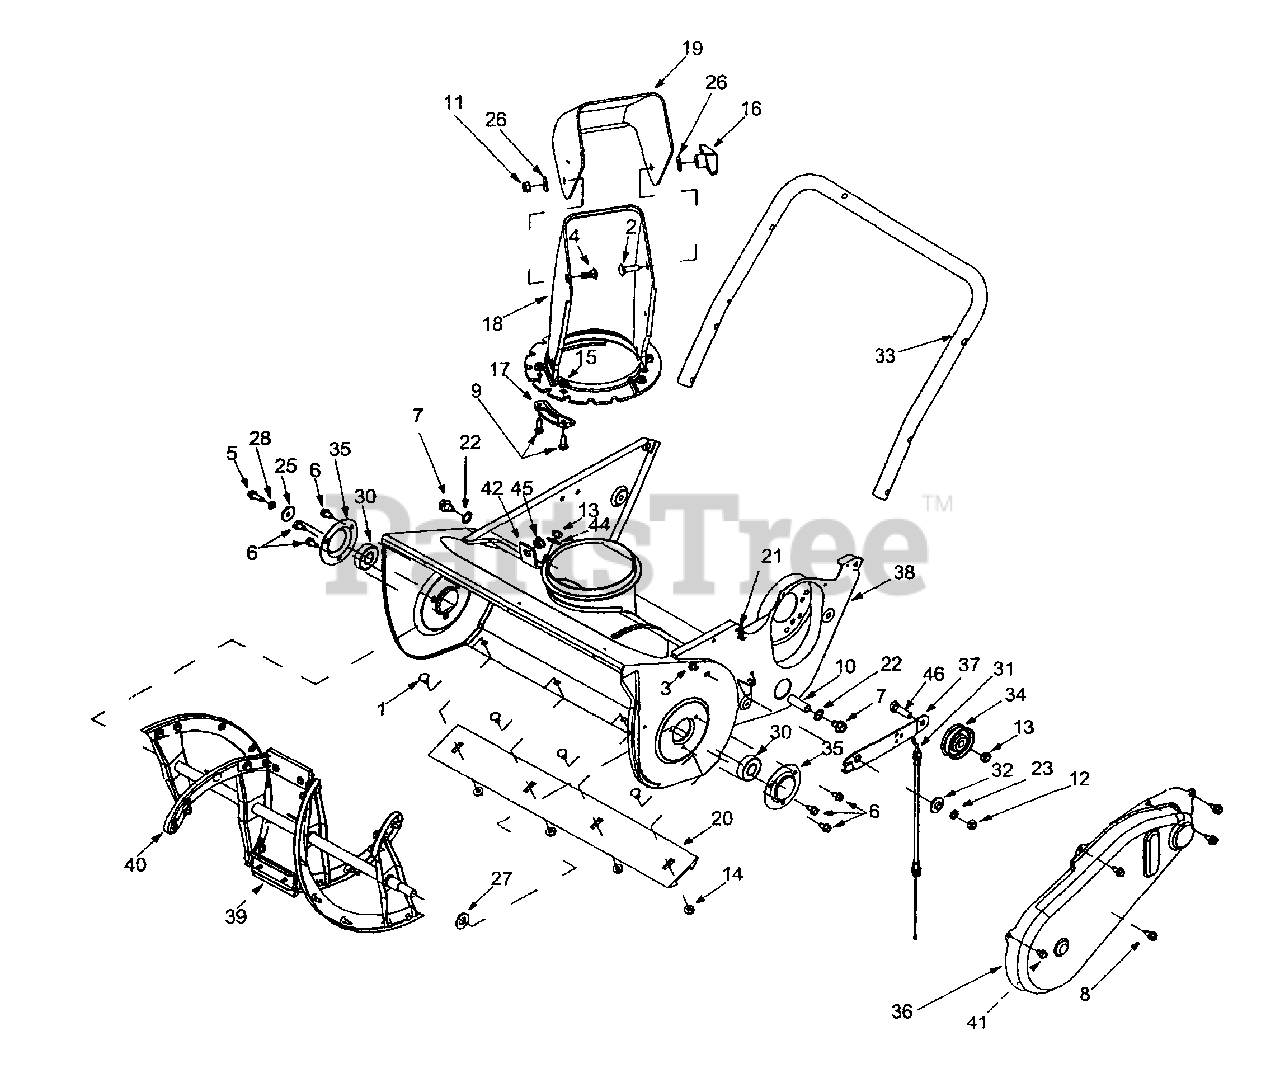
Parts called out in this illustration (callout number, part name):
1	Carriage Bolt
2	Carriage Bolt
3	Pan Head Screw
4	Carriage Bolt
5	Hex Washer Screw
6	Hex Washer Screw
7	Hex Washer Screw
8	Hex Washer Screw
9	Hex Cap Screw
11	Hex Center Lock Nut
12	Hex Nut
13	Hex Lock Nut
14	Hex Lock Flanged Nut
15	Hex Lock Flanged Nut
16	Knob
17	Chute Keeper
18	Lower Chute
19	Upper Chute
20	Shave Plate
21	Extension Spring
22	Flat Washer
23	Lock Washer
25	Flat Washer
26	Washer
27	Flat Washer
28	Lock Washer
30	Ball Bearing
31	Cable-Clutch
32	Spacer
33	Handle-Lower
34	Flat Idler
35	Bearing Cup
37	Idler/Brake Bracket
40	Auger Rubber Replacement Kit
41	Hex Washer Screw
42	Crank Bracket
44	Bell Washer
45	Bushing
46	Hex Screw
